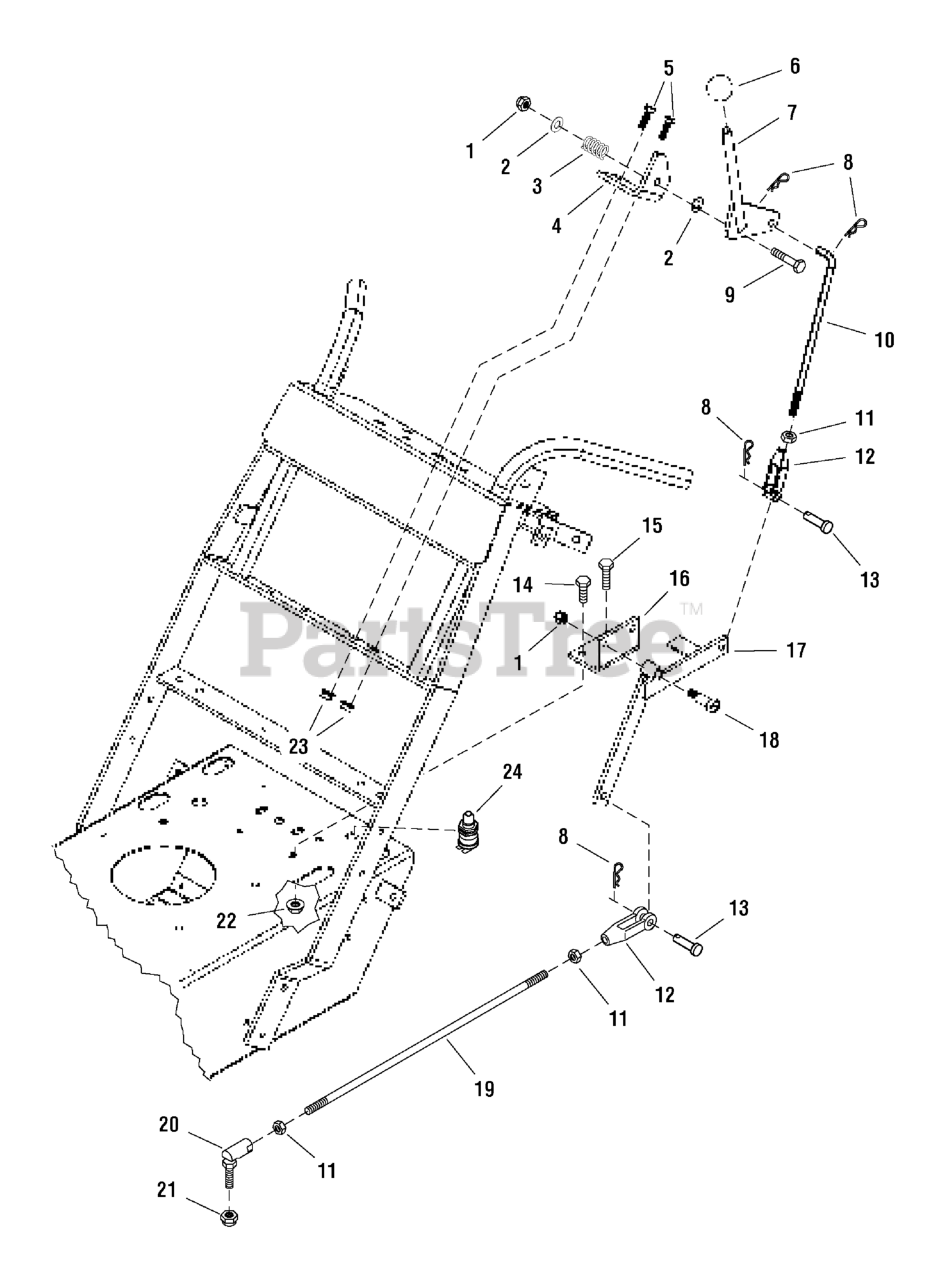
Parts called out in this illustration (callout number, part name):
1	NUT, 3/8-16 HEX NYLON LOCK
2	WASHER, 3/8 SAE
3	SPRING, Compression
4	BRACKET, Shifter
5	BOLT, 5/16-18 X 1 GD5 YZ
6	KNOB
7	LEVER, Blade Engagement
8	HAIRPIN CLIP
9	BOLT, 3/8-16 X 1-3/4" GD5 CZ
10	ROD, Blade Engagement
11	NUT, 3/8-24 Hex
12	CLEVIS, 3/8-24, Plastic
13	CLEVIS PIN, 3/8 x 1
14	BOLT, 3/8-16 X 1" GD5 CZ
15	BOLT, 3/8-16 X 1-1/4" GD5 CZ
16	PIVOT MOUNT
17	BLADE ENGAGEMENT PIVOT
18	SHOULDER BOLT, 1/2 x 1
19	ROD, Blade Engage
20	BALL JOINT, 3/8" Female Studded
21	NUT, 3/8-24 Hex Nylon Lock
22	NUT, 3/8-16 Hex Serrated Flange
23	NUT, 5/16-18 HEX SERRATED FLANGE (LARGE)
